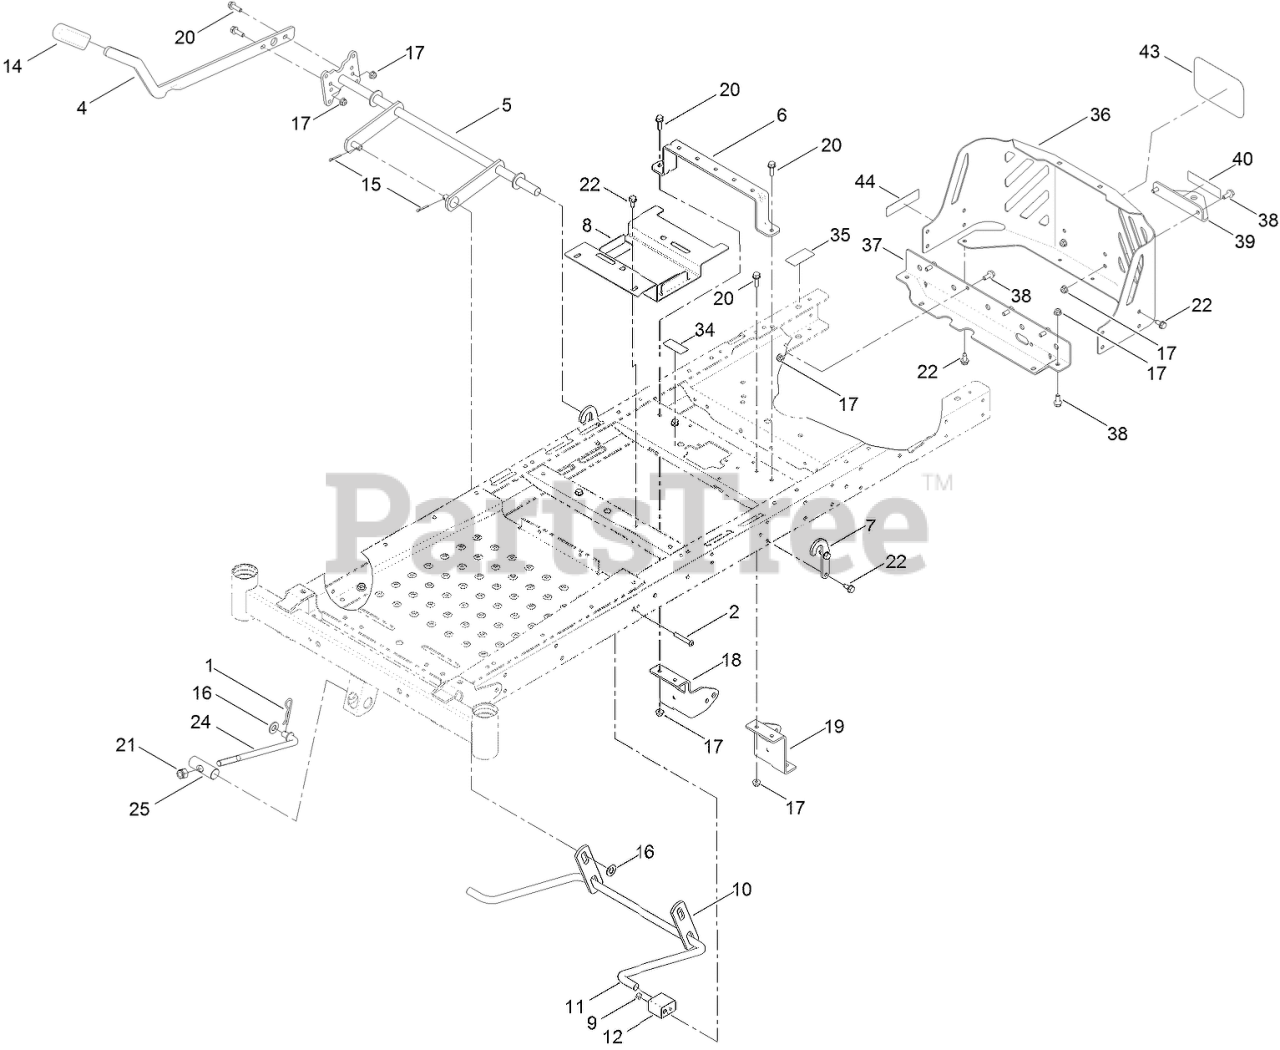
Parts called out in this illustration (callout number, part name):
1	PIN-COTTER
2	SCREW-HSBH
4	LEVER-LIFT
5	LIFT-DECK, NARROW
6	BRACE-SEAT, REAR (NARROW)
7	BRACKET-LIFT
8	BRACKET-BATTERY
9	NUT-LOCK, NI
10	LINK-LIFT
11	ARM-LIFT, REAR
12	BLOCK-PIVOT
14	GRIP-LEVER
15	PIN-COTTER
16	WASHER-FLAT
17	NUT-HF, NI
18	MOUNT-HYDRO, FRONT (RH)
19	MOUNT-HYDRO, FRONT (LH)
20	SCREW-HHF
21	NUT-HEX
22	SCREW-HWHTF
24	ROD-MOUNT, DECK
25	PIN-PIVOT
34	DECAL-LOCATION, SERVICE DEALER
35	DECAL-BYPASS
36	GUARD-ENGINE, NARROW
37	CROSSMEMBER-REAR, NARROW
38	SCREW-HHF
39	BRACKET-HITCH
43	DECAL
44	DECAL-ARRESTER, SPARK
